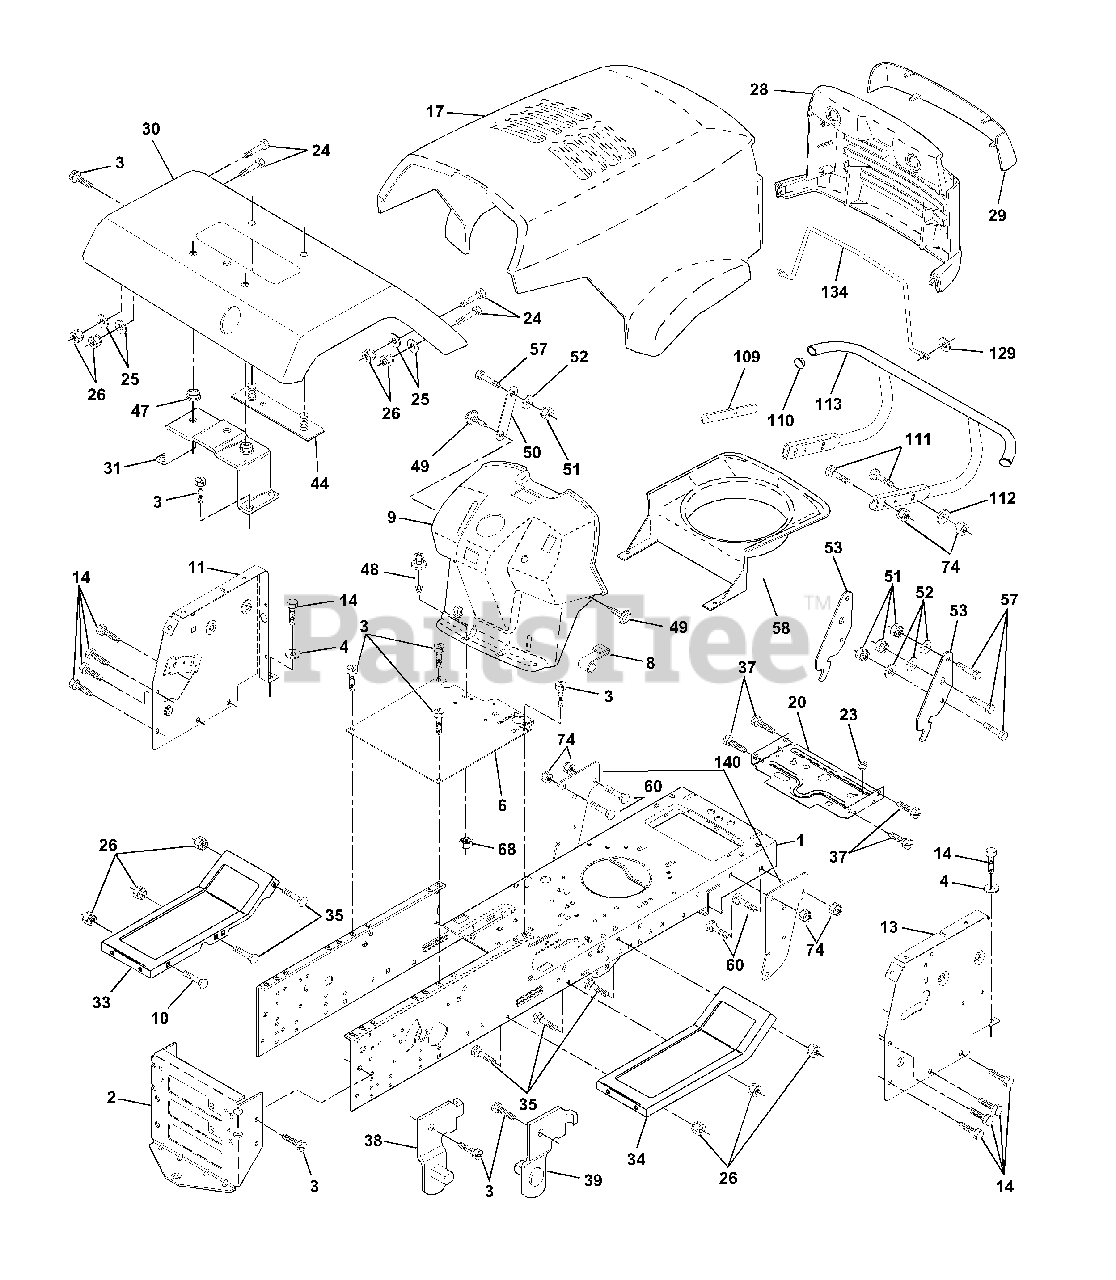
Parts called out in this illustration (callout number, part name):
1	Chassis Weldment 11ga
2	Drawbar, Stretch
3	Screw Thdrol 3/8-16x3/4 Ty-tt
4	Washer 13/32 x 3/4 x 16 Ga.
6	Saddle LT Fender Shift
8	Clip Insulator .406 Mtg Hole
9	Dash P/L w/amm w/HM w/PTO Grey
10	Bolt Carriage 3/8-16 x 1
11	Panel Pnt Dash Lh
13	Panel Dash Rh Asm
14	Screw Thdrol 3/8-16x1/2 Ty-tt
17	Hood LT/PL Husqvarna
20	Plate Mtg. Battery Fuel Tank. 95
24	Bolt Fin Hex 3/8-16unc X 1 Gr. 5
25	Washer 13/32 X 13/16 X 12 Ga
26	Nut Lock Hex W/Ins 3/8-16 Unc
28	Grille LT/PL Husqvrna
29	Lens LT/PL Husqvrna
30	Fender YT/GT w/Shift w/Fuel 94
31	Bracket Asm Fender
33	Footrest Pnt Lh LT/YT/GT 95
34	Footrest Pnt Rh LT/YT/GT 95
35	Bolt Rdhd Sht Sqnk 3/8-16 X3/4
37	Screw Thdrol 5/16-18 X1/2
38	Bracket, Asm. Pivot, L.H., Mower Rear
39	Bracket, Asm. Pivot, R.H., Mower Rear
44	Strap asm Fender
47	Nut, Push Nylon
48	Rivet Push Plate D Plastick Blk
49	Screw Hexwsh. Thdrol 1/4-20 x 3/4
51	Nut Lock Hex W/Ins 1/4-20
52	Washer 9/32 x 7/8 x 16 Ga.
53	Bracket Pnt. Pick off LT/PL Husq.
57	Bolt Hex 1/4-20 x 3/4
58	Air Duct CV18
60	Bolt Rdhd Sqnk 3/8-16unc x 3/4
68	Nut Keps Hex 1/4-20
74	Nut Crownlock 3/8-16 UNC
109	Bracket Extension Bumper
110	Plug Plastic
111	Bolt Carriage 3/8-16 x 1-1/4
112	Washer 13/32 x 13/16 x 16 Ga.
113	Bumper Asm.
129	Washer 9/32 x 5/8 x 16 Ga.
134	Rod Support Hood LT/PL Husq.
140	Bracket Chassis Front 7 Ga.
